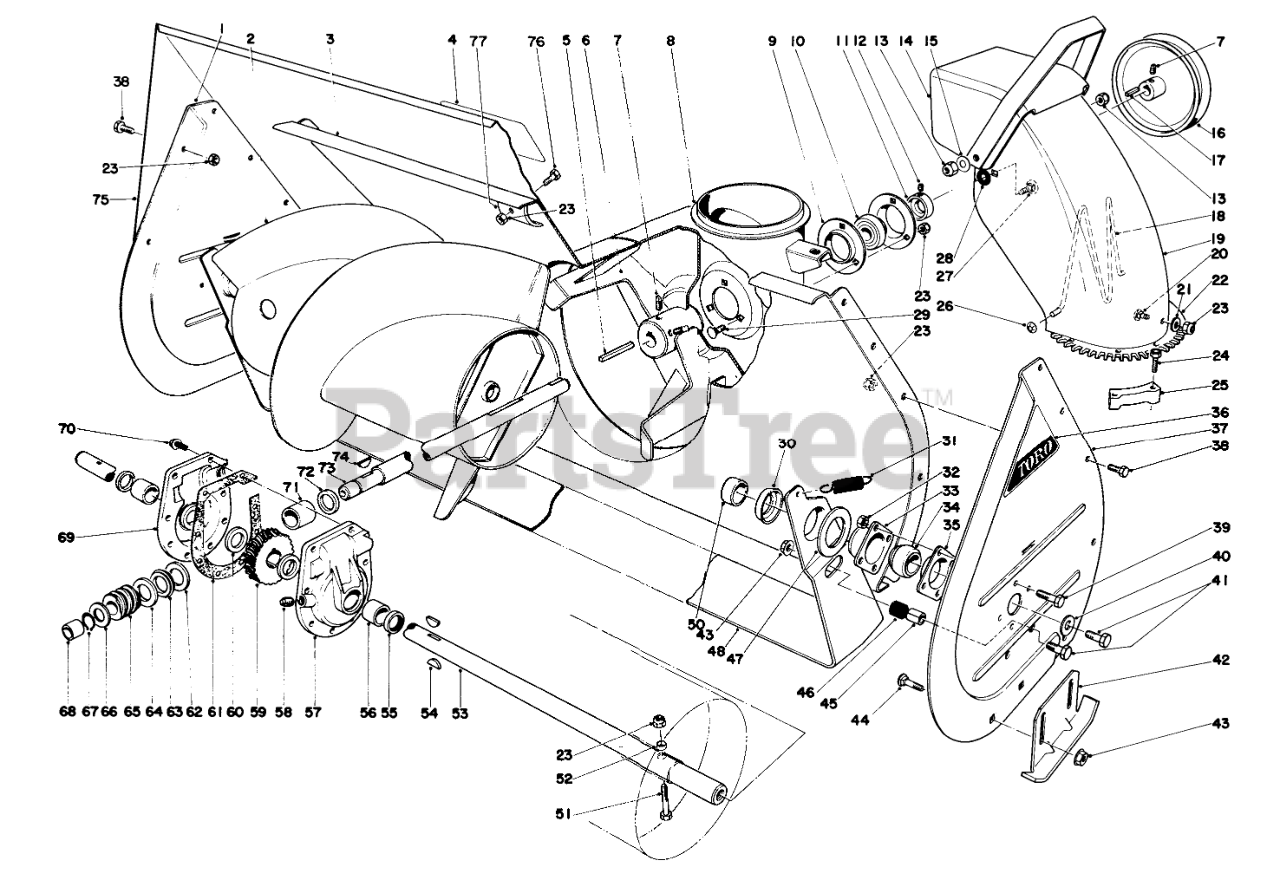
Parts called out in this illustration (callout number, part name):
1	RH AUGER SIDE PLT R
2	RH AUGER ASM - 32"
3	AUGER HSG WA 32" R
4	Decal
6	IMPELLER ASM
7	SCREW-SET, SQH
8	CHUTE RING
9	BRG FLANGE
10	BALL BRG W/COLLAR
11	EXT LOCKING COLLAR
12	SCREW-HSH
13	NUT-LOCK, CONE
14	Deflector
15	WASHER-BELLEVILLE
16	1/2 X 9.5 DIA PULLEY
17	SQUARE KEY
18	WIRE-CHUTE
19	Upper Chute
20	SCREW-CARR
21	WASHER-PLAIN
22	Screw
23	NUT-LOCK, NI
24	SCREW-SPECIAL
25	RETAINER-CHUTE
26	NUT-PUSH
27	SCREW-CARR
28	Rubber Washer
29	BOLT-CARR
30	Positioner-Scraper
31	SPRING-TENSION
32	NUT-LOCK, CONE
33	BEARING-FLANGE, FRONT
34	BEARING
35	BEARING-FLANGE, REAR
36	AUGER SIDE PLT DECAL
37	LH AUGER SIDE PLT R
38	SCREW-HH
39	SCREW-HH
40	WASHER
41	SCREW-HH
42	AUGER SKID WA R
43	NUT-HF
44	SCREW-CARR
45	SCRAPER STOP SPACER
46	SCRAPER STOP CUSHION
47	SCRAPER BLADE SPACER
48	SCRAPER BLADE 32" R
50	AUGER SPACER
51	Auger Bolt
52	SPACER-HUB, AUGER
53	32 AUGER SHAFT
54	KEY-WOODRUFF
55	SEAL-OIL
56	BUSHING
57	Gear Case L.H. (Incl. Ref. #55-56)
58	PLUG-PIPE, SQH
59	GEAR-WORM, 27T
60	WASHER-THRUST
61	asket
62	WASHER-THRUST
63	BEARING-THRUST
64	THRUST-WASHER
66	WASHER-THRUST
67	Ring-Snap
68	BUSHING
69	Gear Case R.H. (Incl. Ref. #55-56)
70	SCREW-TAPTITE
71	BUSHING-SPECIAL
72	RING-QUAD
73	SHAFT-IMPELLER
74	KEY-WOODRUFF
75	Auger Extension
76	SCREW-HH
77	SHIELD CLAMP R
